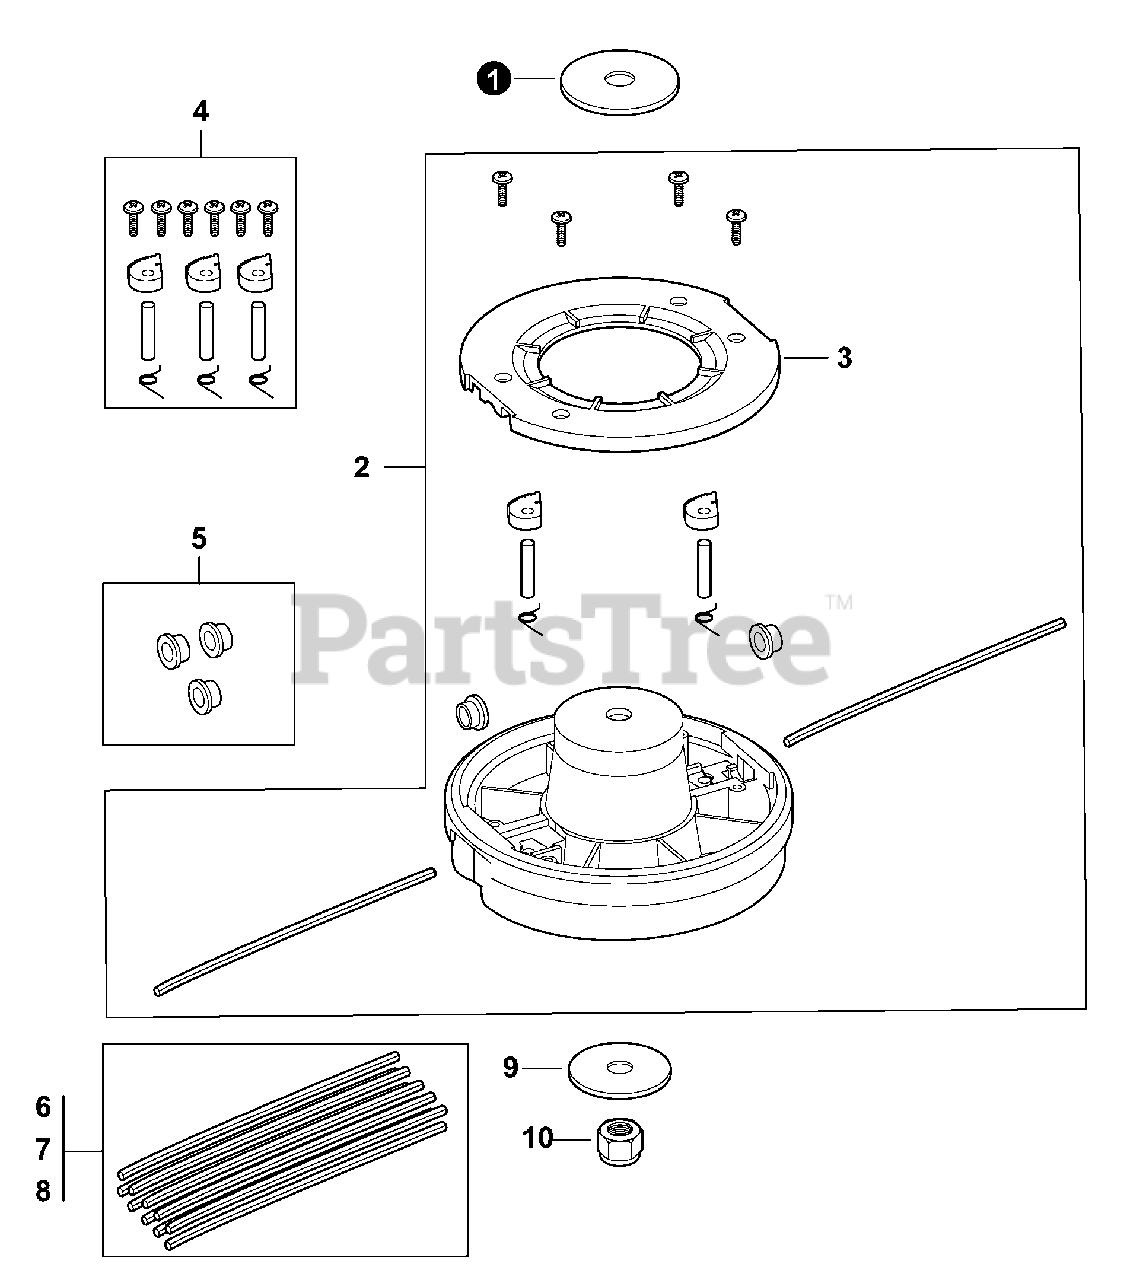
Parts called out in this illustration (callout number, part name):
1	WASHER 10
2	TRIMMER HEAD - RAPID-LOADERT
3	COVER, TOP
4	PAWL KIT
5	EYELET (PACKAGE OF 3)
6	LINE, TRIMMER - 0.095 DIA. (PKG. OF 10)
7	LINE, TRIMMER - 0.095 DIA. (PKG. OF 20)
8	LINE, TRIMMER - 0.095 DIA. (PKG. OF 50)
9	WASHER 10
10	NUT, LOCK
